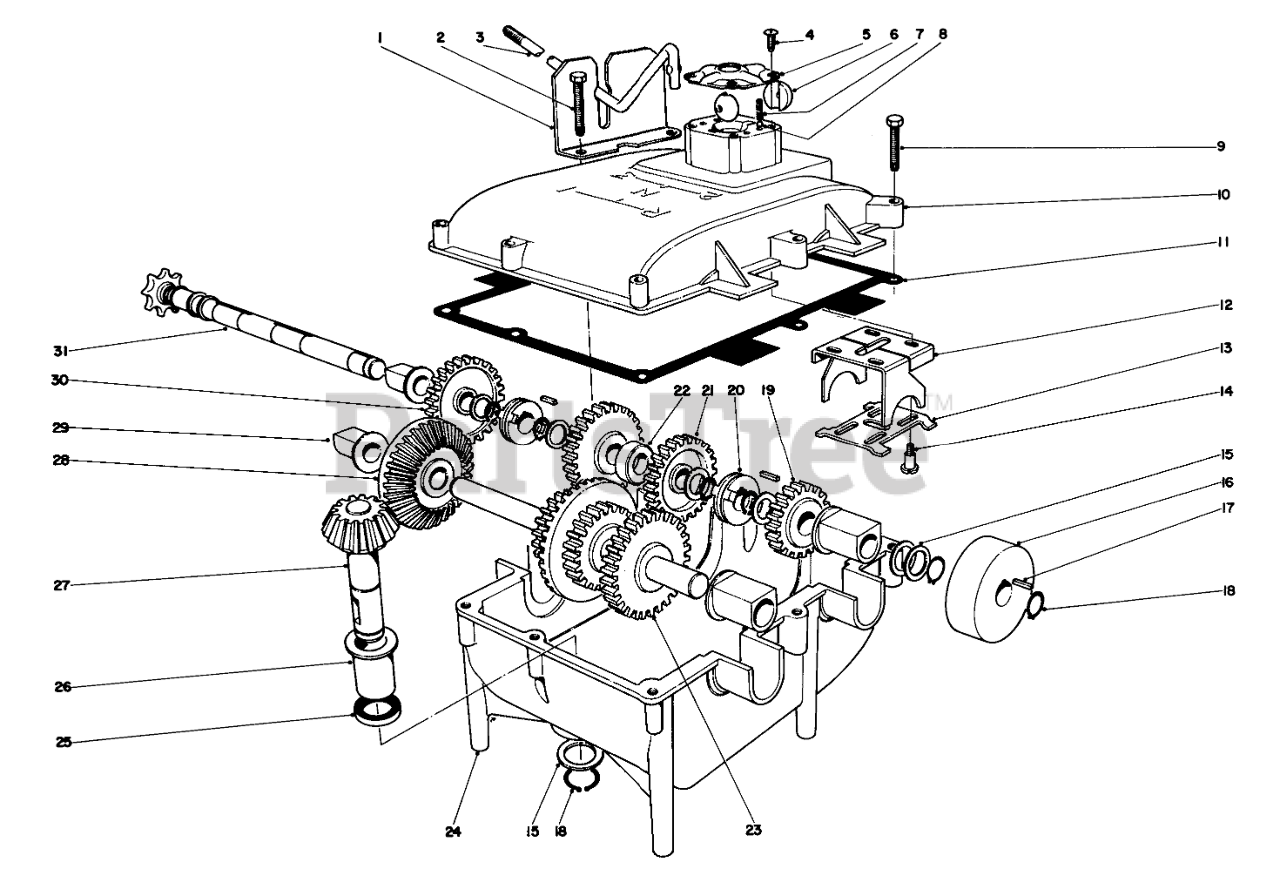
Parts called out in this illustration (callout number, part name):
1	Bracket Shift
3	Shift Rod
5	Cap Shift
7	Spring
8	Ball-Detent
10	Upper Gear Cover Housing
11	Gasket
12	Yoke Shift
13	Backing Plate
14	Screw Shoulder
15	Flat Washer
16	Brake Drum
17	Square Key
18	RING-SNAP, EXTERNAL
19	Gear-24 Teeth
20	Dog Driving
21	Gear-30 Teeth
22	Spacer
23	Assembly-Drive Shaft
24	Housing Gear
25	Grease Seal
26	Bushing
27	Assembly-Pinion Shaft
28	Bevel Gear
29	Bearing
30	Gear 36 Tooth
31	Shaft Sprocket
